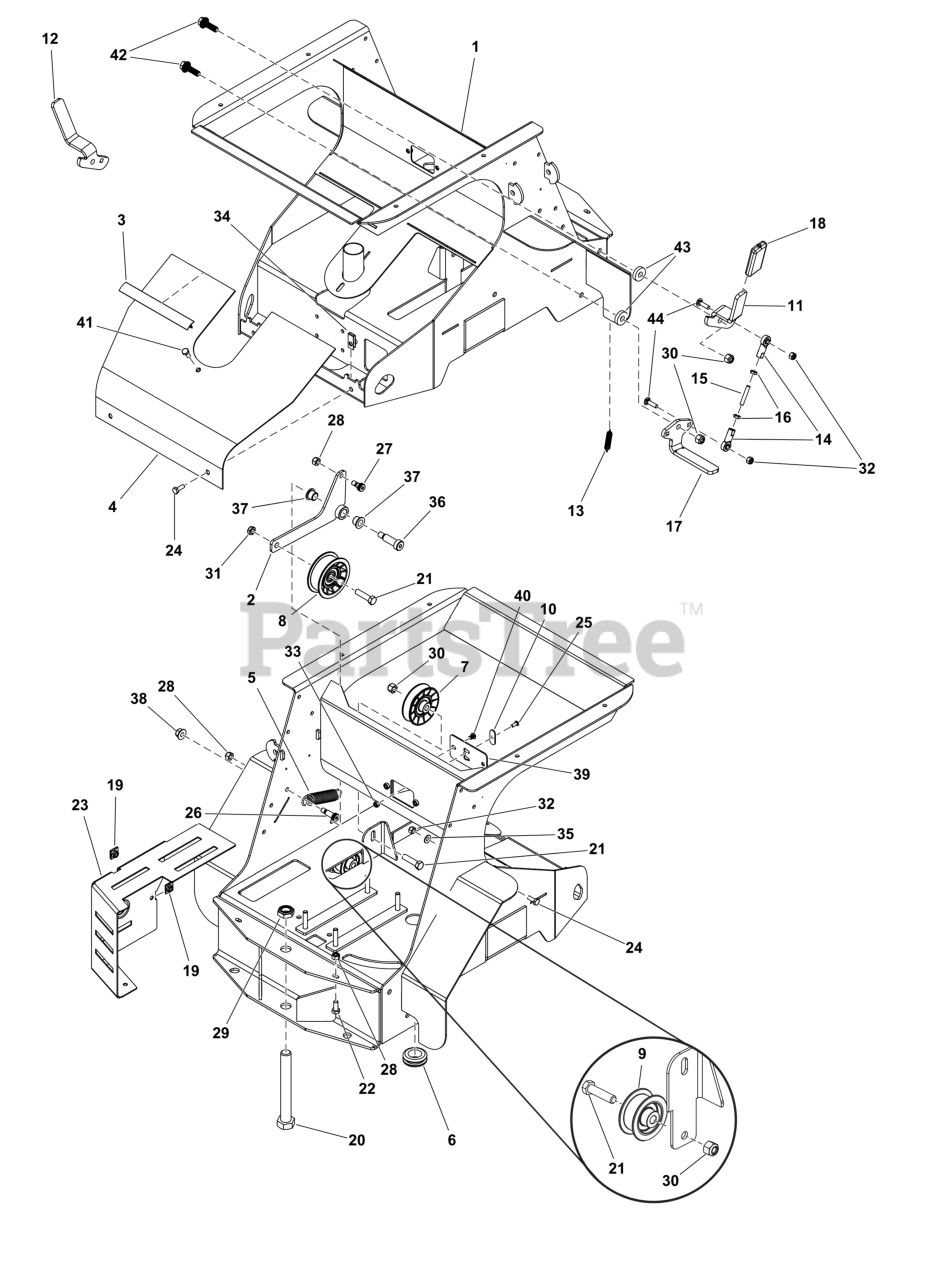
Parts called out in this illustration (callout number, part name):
1	FRAME
2	WELD, ARM IDLER ROVER
3	SEAL TRIM, FRONT COWL 7" LONG
4	FRONT COWL, ROVER (SANDED)
5	SPRING, EXTENSION .840" OD X 4.00" LONG SS
6	GROMMET 1.00" I.D. FIT 1.38"HOLE
7	PULLEY V-BELT IDLER 1.79" OD X 3/8" BORE
8	PULLEY IDLER 2.75" OD X 3/8" BORE
9	PULLEY IDLER 1.75" OD X 3/8" BORE
10	PLATE, CABLE HOLDER
11	HANDLE, LH
12	HANDLE, RH
13	SPRING, EXTENSION .375" OD X 2.500 LONG SS
14	ROD END, FEMALE 1/4-28 RH SS PTFE RACE
15	ROD, THREADED .250"-28 X 1.500" SS188
16	NUT-HEX, JAM .250"-28 SS188
17	ARM, Brake
18	GRIP, .188" X 1.00" ID X .150" THK CLSD CELL FOAM
19	NUT-CLIP, .250"-20 X .375" EDGE DISTANCE
20	SCR-CAP, HEX .750"-10 X 6.000" SS188
21	SCR-CAP, HEX .375"-16 X 1.500" SS188
22	SCR-CAP, HEX .3125"-18 X .750" SS188
23	PLATE, Guard
24	SCR-CAP, HEX .250"-20 X .750" SS188
25	SCR-CAP, BSH #10-24 X .500" SS188
26	BLT-SLDR, SH .38"X0.75,.313-18 X.50 SS
27	BLT-SLDR, SH .375" X 0.250", .3125"-18 X.500" SS188
31	NUT-HEX-NYLK, .375"-16 TH SS188
34	NUT, Clip
35	WSHR-STL, FLT .281" X .625" X .050" IS SS188
36	BLT-SLDR,SH.50"X1.25",.375"-16X.63"SS188
37	BSHG-FL, .500" X .625" X .500", .875"x .062" IR
38	NUT-HEX-NYLK, FLG .375"-16 SS188
39	PLATE, HOPPER CABLES
40	SCR-CAP, SBH .250"-20 X .375" SS188
41	SCR-CAP, HEX .250"-20 X .625" SS188
42	SCR-CAP, HSWH .375"-16 X 1.250" SS188
44	BLT-RDHDSQNK, .250"-20 X 1.000" SS188
